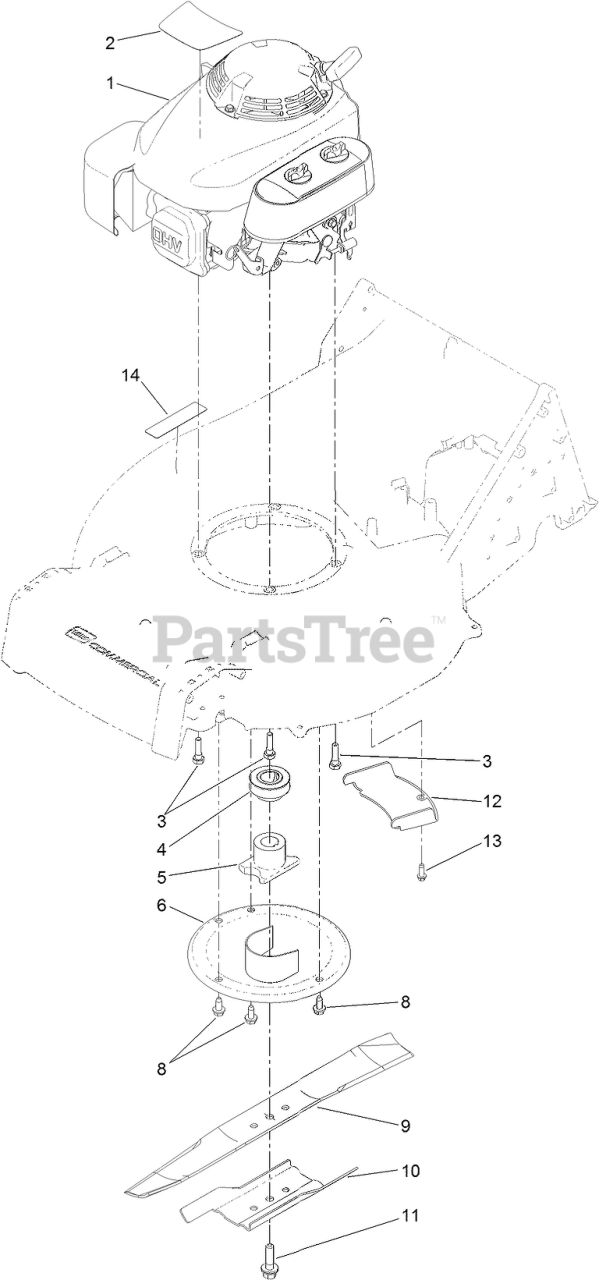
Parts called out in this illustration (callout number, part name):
1	ENGINE-HONDA, GXV160UH2 A1TT
2	DECAL-ENGINE, HONDA
3	SCREW-HHSH
4	PULLEY-DRIVER
5	DRIVER-BLADE
6	PROTECTOR-CRANKSHAFT
8	SCREW-HWHTF
9	BLADE-RECYCLING
10	ACCELERATOR-BLADE
11	BOLT-BLADE
12	COVER-BELT
13	SCREW-HWHTF
14	DECAL-ARRESTER, SPARK
